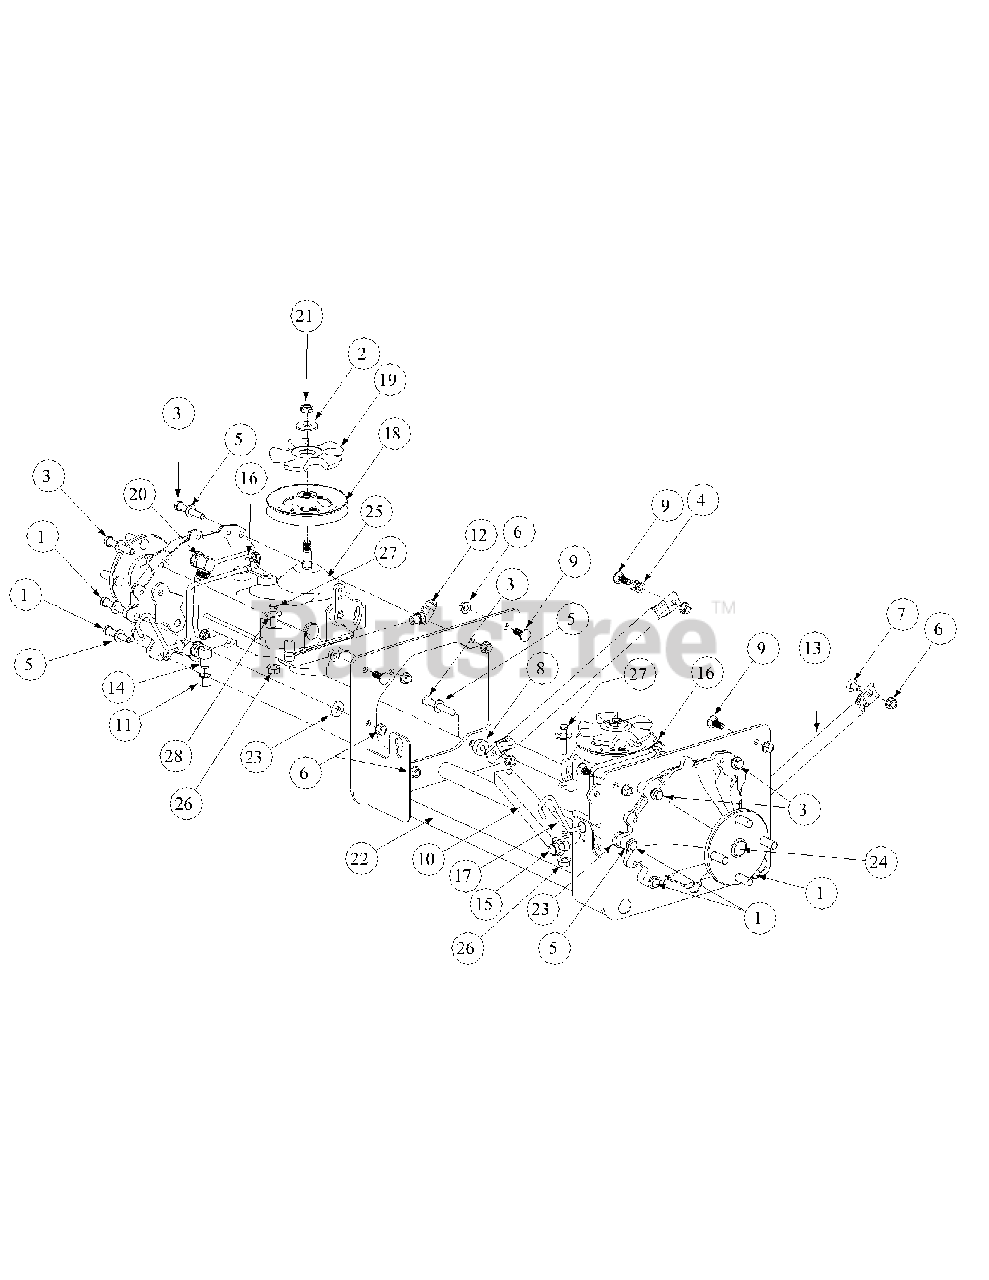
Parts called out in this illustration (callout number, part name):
1	Hex Cap Screw, 3/8-16 x 2
2	Flat Washer, 1/2
3	Hex Cap Screw, 3/8-16 x 2.5
4	Lock Washer, 3/8
5	Flat Washer, 3/8
6	Flange Lock Hex Nut, 3/8-16
7	Carriage Bolt, 3/8-16 x .75 Long
8	Spacer, .406 ID x 1.00 OD x .38
9	Carriage Bolt, 3/8-16 x 1
10	Pump Support Angle
11	Nut Cap, 3/8
12	Elbow Fitting, 3/8 - 1/2 x 45°.
14	Elbow Fitting, 3/8 x 3/8
15	Fitting, 1/2 x 3x8
16	Cotter Pin, .072 x 1.12 Long
17	Pump Release Rod
18	Slotted Hydro Pulley
19	Pulley Hydro Fan
20	Elbow Fitting, O-Ring 3/8, 1/2 Flare
21	Insert Lock Jam Nut, 1/2-20
22	Sub-Frame Weldment
23	Flat Washer, .385 x 1.0 OD x .13
24	Right Hand Pump Assembly
25	Left Hand Pump Assembly
26	Hex Flange Lock Nut, 5/16-18
27	Hex Cap Screw, 5/16-18 x 2
28	Flat Washer, 5/16
